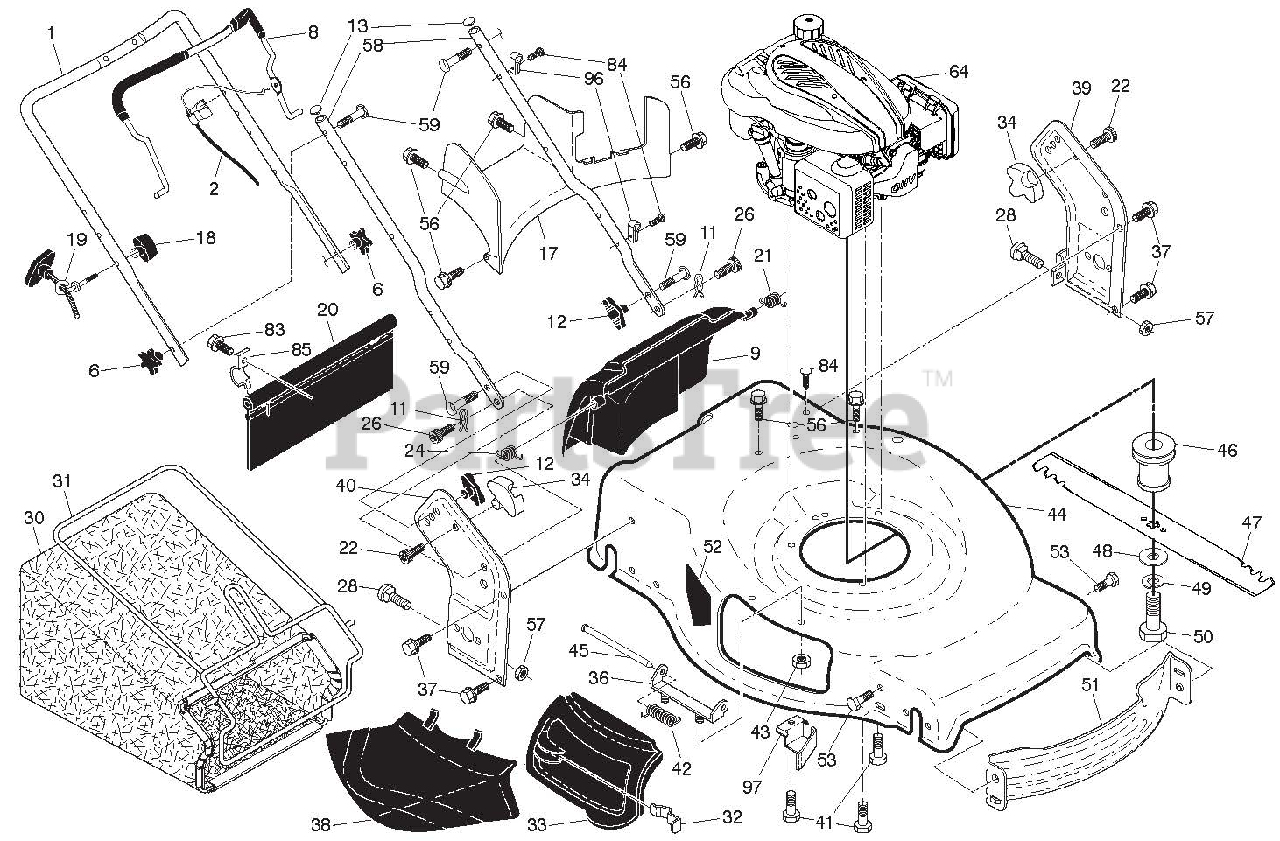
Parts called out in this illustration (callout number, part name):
1	UPPER HANDLE ASSEMBLY
2	CABLE, ENGINE ZONE CONTROL
6	Handle Knob
8	CONTROL BAR
9	REAR DOOR ASSEMBLY
11	HAIRPIN, DOOR/HANDLE PIVOT
12	HANDLE KNOB, STANDARD
13	PLUG, HANDLE BAR
17	REAR BAFFLE
19	ROPE GUIDE
20	REAR SKIRT
21	SPRING, REAR DOOR, LH, BLACK
22	SCREW, PANHEAD, TORX #20
24	SPRING, REAR DOOR, RH, GREY
26	SCREW, REAR DOOR/HANDLE PIVOT
28	BOLT, CARRIAGE
30	GRASSBAG
31	FRAME, GRASSBAG
32	LATCH, MULCHER DOOR
33	MULCHER DOOR
34	BRACKET, GRASSBAG
36	Hinge Bracket Assembly
37	BOLT.5/16-18HEX.WHS.HD.LCKSERR
38	DISCHARGE DEFLECTOR
39	HANDLE BRACKET, LH
40	HANDLE BRACKET, RH
41	Screw, Hex Head, Threaded, Rol
42	Spring, Torsion
43	LOCKNUT, HEX 1/4-20
44	KIT, LAWN MOWER HOUSING
45	Rod, Hinge
46	BLADE ADAPTER
47	BLADE 22"
48	Hardened Washer
49	Helical Lockwasher
50	Bolt, HEX .44-20 1.5 GRD 8
51	FRONT BAFFLE
52	DECAL, WARNING
53	BOLT.5/16-18HEX.WHS.HD.LCKSERR
56	Screw, Rear Baffle
57	NUT, HEX
58	BAR, LOWER HANDLE
59	Handle Bolt
64	ENGINE,LNCN T322002896-2131008
84	FASTENER, PUSH
85	MOUNTING BRACKET, REAR SKIRT
96	Clip, Cable
97	BELT KEEPER
